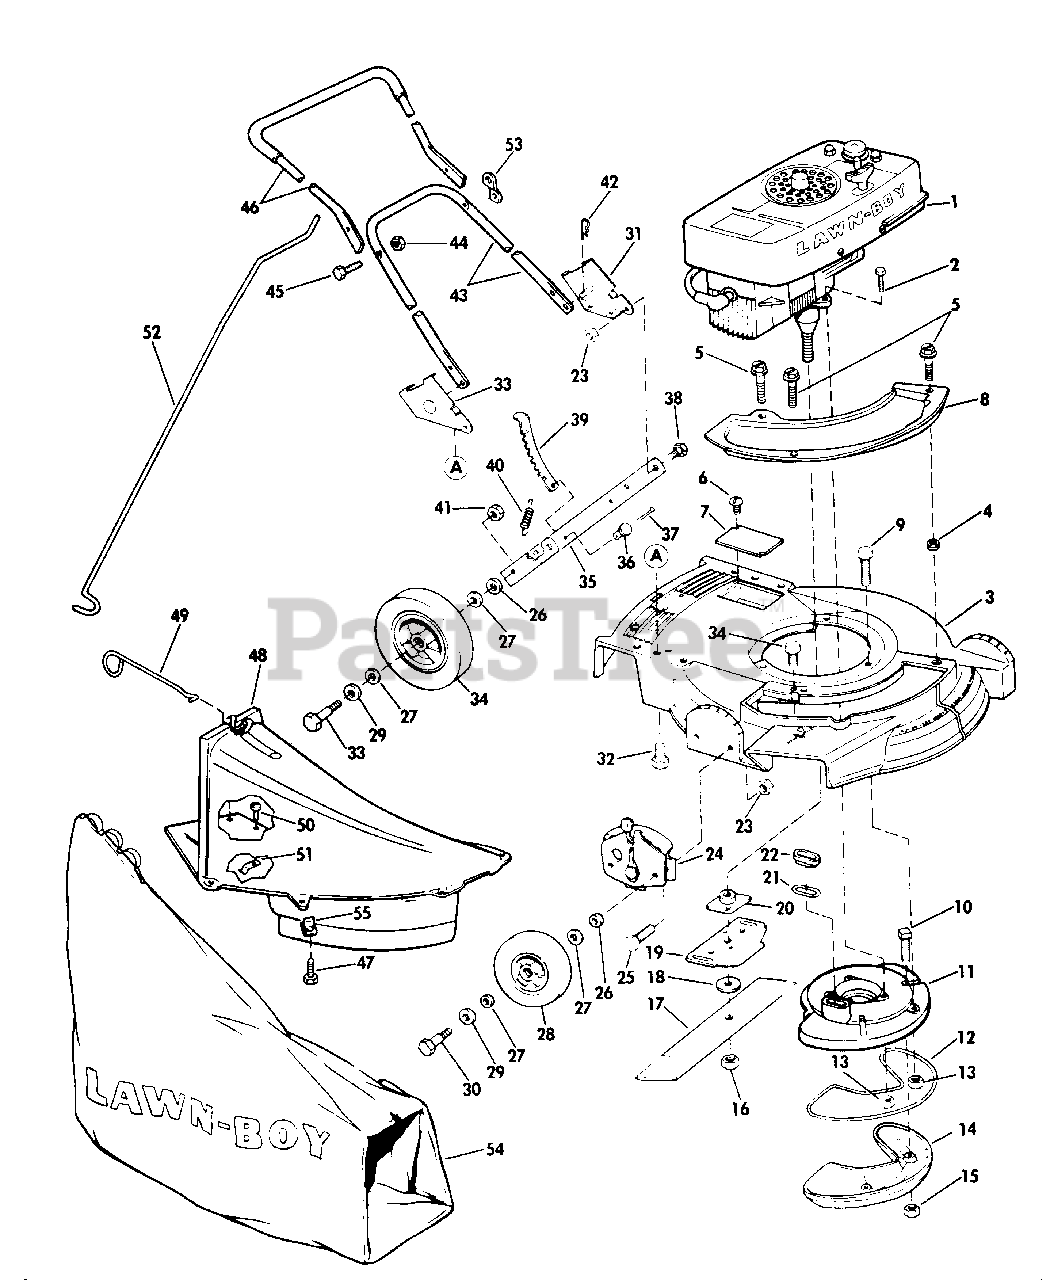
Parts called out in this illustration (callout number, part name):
1	Engine-D-432
2	Screw-Crankcase to Muffler Plate
3	Housing & Cover Plate-21"
4	Grommet (Also Included in 679172 19" Housing)
5	Screw (Also for 19" Models)
6	Drivescrew (21" Models Only)
7	Cover (21" Models Only)
8	Cover-Chute (19" & 21" Models)
9	Screw-Muffler Plate to Housing
10	Screw-Muffler to Muffler Plate
11	Muffler Plate
12	Gasket-Muffler
13	Nut
14	Muffler
15	Nut-Muffler
16	Nut-Blade
17	Blade-21"
17	Blade-l9"
18	Washer (21" Models Only)
19	Stiffener-Blade
20	Collar & Plate Assembly
21	Gasket-Exhaust
22	Sleeve-Muffler Gasket
23	Nut
24	Height Adj. Assembly
25	Screw-Height Adj. Bracket
26	Washer
27	Felt Washer
28	Wheel & Tire-6"
29	Washer-Wheel Bolt Head
30	Bolt-Shoulder, Wheel Front
31	Bracket-Handle-Left
32	Screw
33	Bracket-Handle-Right
33	Bolt-Rear Wheel
34	Wheel & Tire-8"
35	Bracket-21"
35	Bracket-19"
36	Pin
37	Cotter Pin
38	Bolt
39	Lever-Height Adj.-Rear
40	Spring
41	Nut
42	Hairpin
43	Handle-Bottom
44	Nut-Handle
45	Screw-Handle
46	Handle-Top
47	Screw-Chute Mounting
48	Chute & Skirt
49	Wheel Guard Assembly
50	Screw
51	Speed Nut
52	Rod & Clip Assembly
53	Clip-Rod
54	Grass Bag
55	Speed Nut
76	Axle & Torque Lug Assy.
